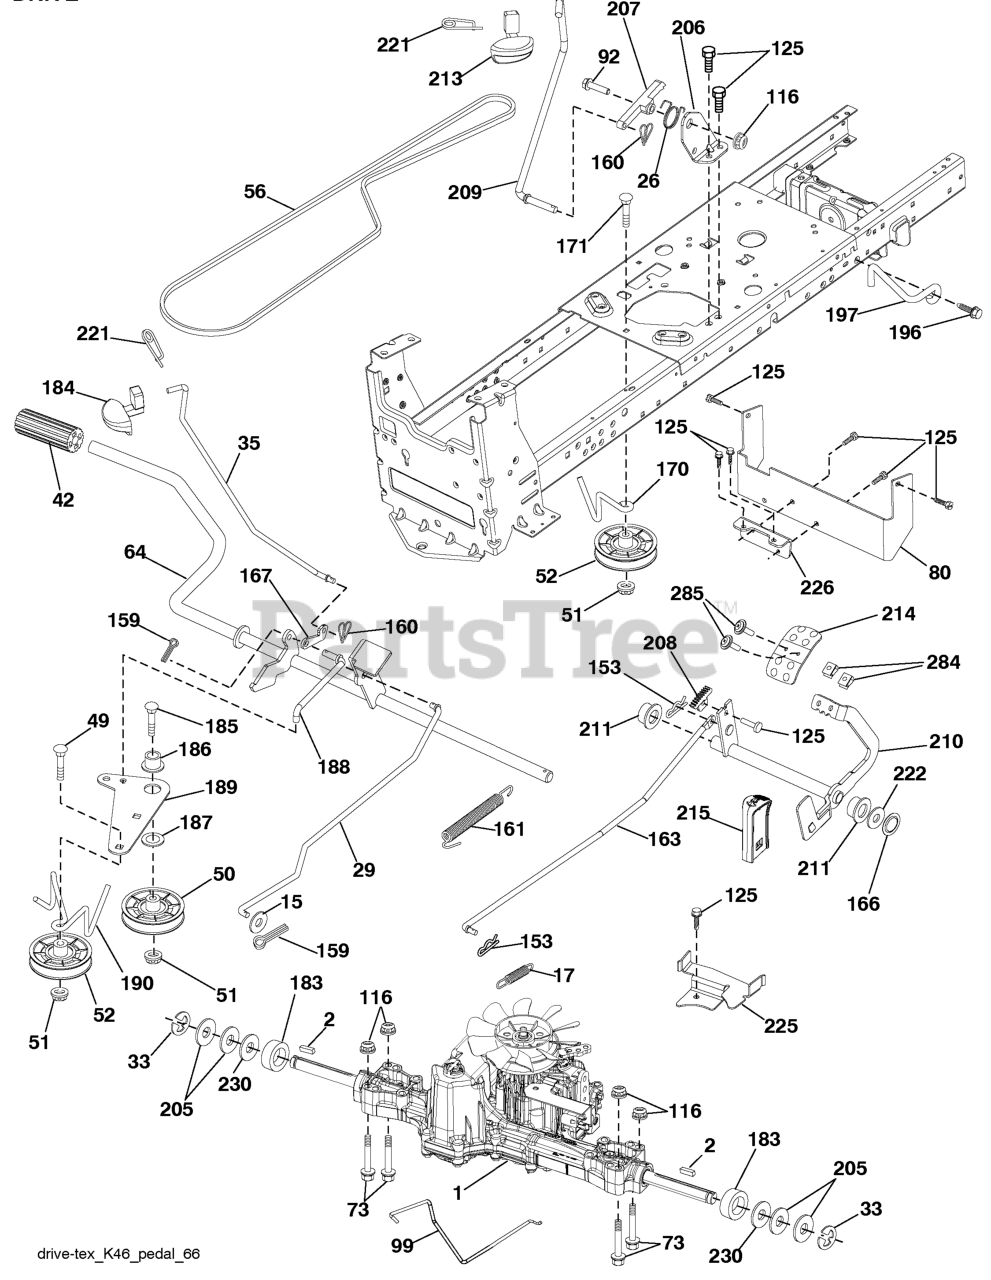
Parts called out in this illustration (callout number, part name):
1	TRANSAXLE(K46BT).PDL.
2	SQUARE KEY
15	WASHER
17	SPRING.BRAKE.K46.GREEN
26	SPRING.RETURN.CRUISE
29	ROD.BRAKE.K46
35	ROD.BRAKE.PARKING.GT.H
42	PEDAL COVER T
50	IDLER.FLAT.910.OFFSET
51	NUT LOCK FLG 3/8-16 UNC
52	IDLER.V-GROOVE.910.OFFSET
56	V-BELT.MOWER.92.40.42/K46
64	SHAFT.ASM.PEDAL.BRK.CNTR
73	BOLT HEX 5/16-18 GR 5
80	STRAP TORQUE
92	BOLT
99	ROD.SPRING.BYPASS.K46.LT.Z
116	NUT LOCK HEX FLANGE 5/16-18
125	SCREW
153	RETAINER M
159	COTTER PIN
160	RETAINER CLIP
161	SPRING, RETURN LT
163	ROD.CONTROL.PEDAL.K46
166	NUT.PUSH.625
167	LATCH.BRAKE.SPRING
170	KEEPER.V-IDLER.CENTER.
171	BOLT
183	SPACER AXLE
184	HANDLE.PARKG.BRK.HUSQ X667
186	SPACER.RETAINER
187	WASHER 12/32X2X10GA
188	RP.LINK.CLUTCH.GROUND.DRIVE
189	BELLCRANK.GROUND.DRIVE.TEX.
190	KEEPER.BELLCRANK.DRIVE
196	SCREW 3/8-16X1
197	LINK.CLUTCH.ANIT-ROTAT
206	BRKT.MOUNT.LATCH.CRUIS
207	LATCH.CONTROL.CRUISE
208	GEAR.SECTOR.CONTROL.CR
209	ROD.CONTROL.CRUISE.GT.
210	ROCKER.ASM.PEDAL.CONTR
211	BEARING.NYLON
213	KNOB.CONTROL.CRUSIE.HU
214	PEDAL.FORWARD.HUSQVARNA.DEALER
215	PEDAL.REVERSE.TEX.GT.4
221	RETAINER.SPRING.CLIP.H
222	WASHER 21/32 X 1-1/4 X 10 GA.
225	KEEPER.BELT.TRANSAXLE.K46
226	BRACKET.MOUNT.TORQUE.K46.TLT
230	WASHER.HARDENED
284	NUT.U-CHNL.1/4-20.550DP.350PNL
285	SCREW.PHD.1/4-20.BOX DRVE
